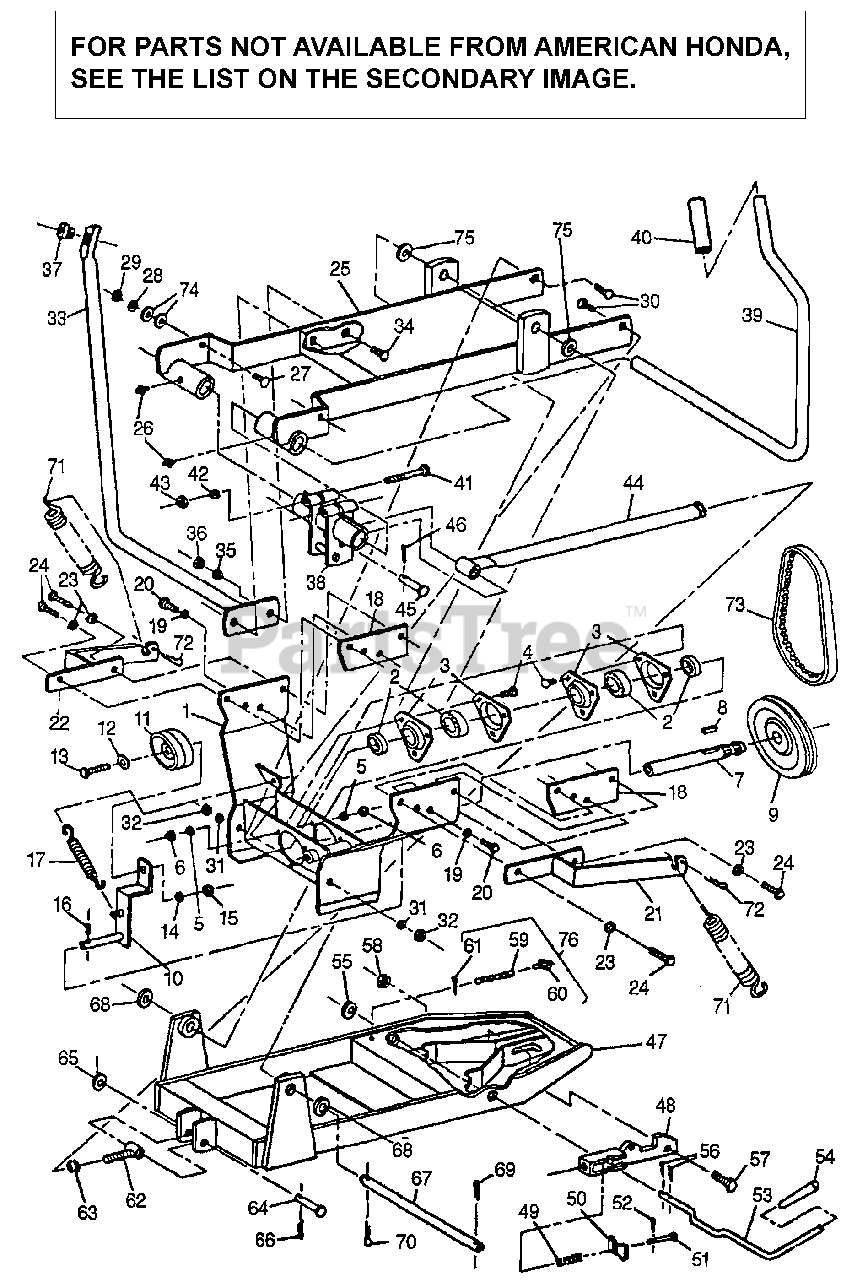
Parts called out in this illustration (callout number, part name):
2	BEARING (W/LOCKING COLLAR)
3	FLANGE, BEARING
8	KEY (1/4X1/4X1 1/4")
11	PULLEY, IDLER
17	SPRING, TENSION
25	SUB-FRAME, RR.
26	FITTING, GREASE
37	GROMMET, PLASTIC
39	ARM, LIFT
44	ARM, LIFT PIVOT
45	PIN (17/32X2-1/4")
48	LATCH, QUICK HITCH
50	PLATE, SPRING
51	PIN (1/4X1-3/4")
53	ARM, LIFT
54	GRIP, RUBBER HANDLE
62	BOLT, SLEEVE
64	PIN (17/32X2-1/8")
67	PIN (5/8X10-1/2")
71	SPRING, TENSIONER
73	BELT (BX37)
